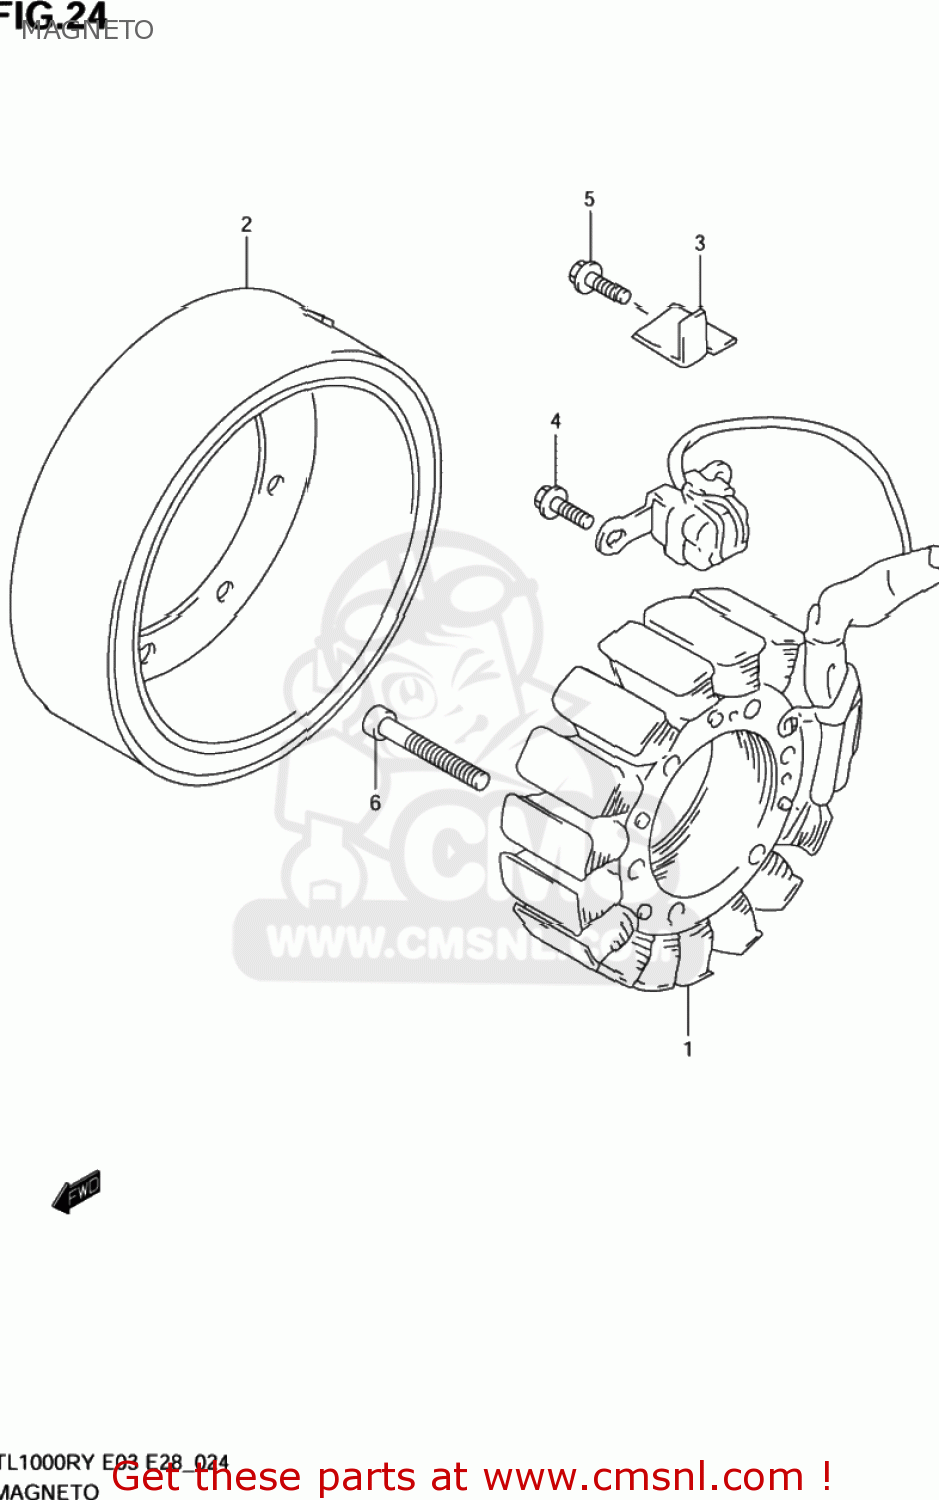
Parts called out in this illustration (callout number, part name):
1	STARTER ASSY
2	ROTOR ASSY
3	CLAMP,MAGNETO LEAD NO.1
4	BOLT
5	BOLT
6	BOLT
